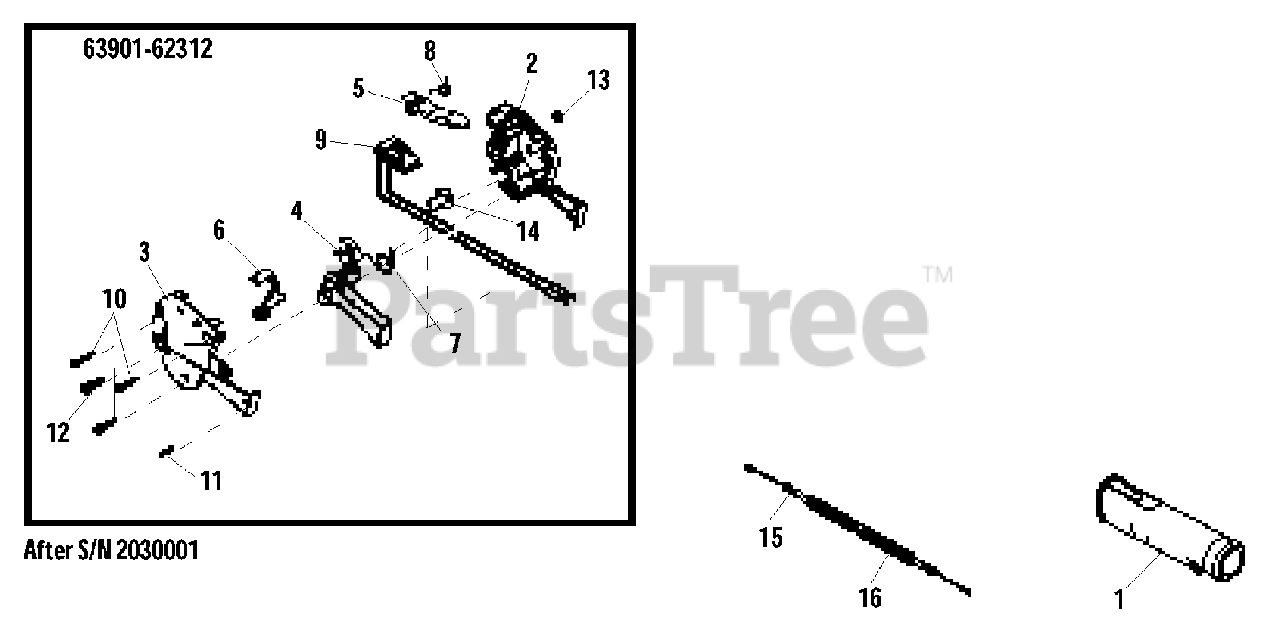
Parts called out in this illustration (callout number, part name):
1	GRIP
2	HANDLE, CONTROL - RIGHT
3	HANDLE, CONTROL - LEFT
4	LEVER
5	LEVER, LOCK
6	HOLDER
7	SPRING
8	SPRING
9	SWITCH, IGNITION
10	SCREW - 4X20 -- TAPPING
11	SCREW - 3X14 -- TAPPING
12	SCREW - 5X20
13	NUT - 5
14	PLUG
15	CABLE, THROTTLE
16	TUBE
63901-62312	THROTTLE LEVER ASSY
